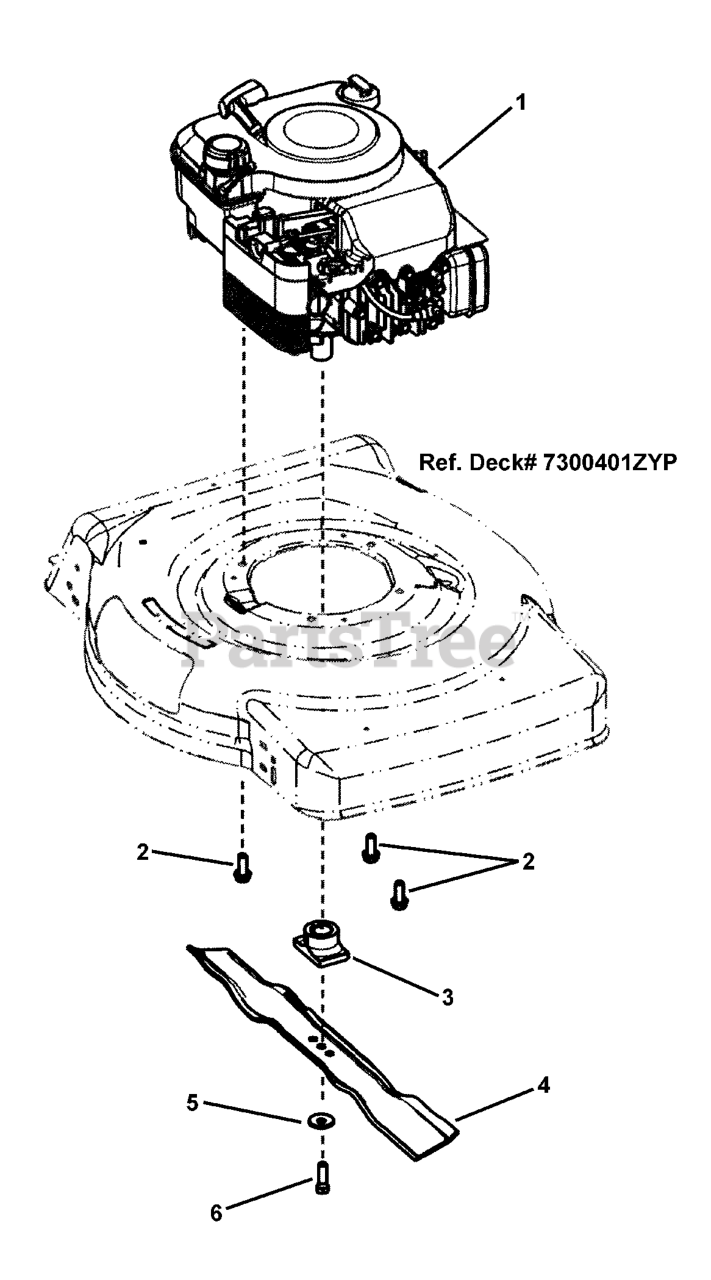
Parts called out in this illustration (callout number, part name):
2	SCREW, 3/8-16 x 1 Hex Washer Self-Tap
3	HUB, Blade, 22"
4	BLADE, 22"
5	WASHER, Bellville, .38 ID x 1.183 OD
6	SCREW, 3/8-24 x 1-1/4 Hex Head Cap, GR 5
